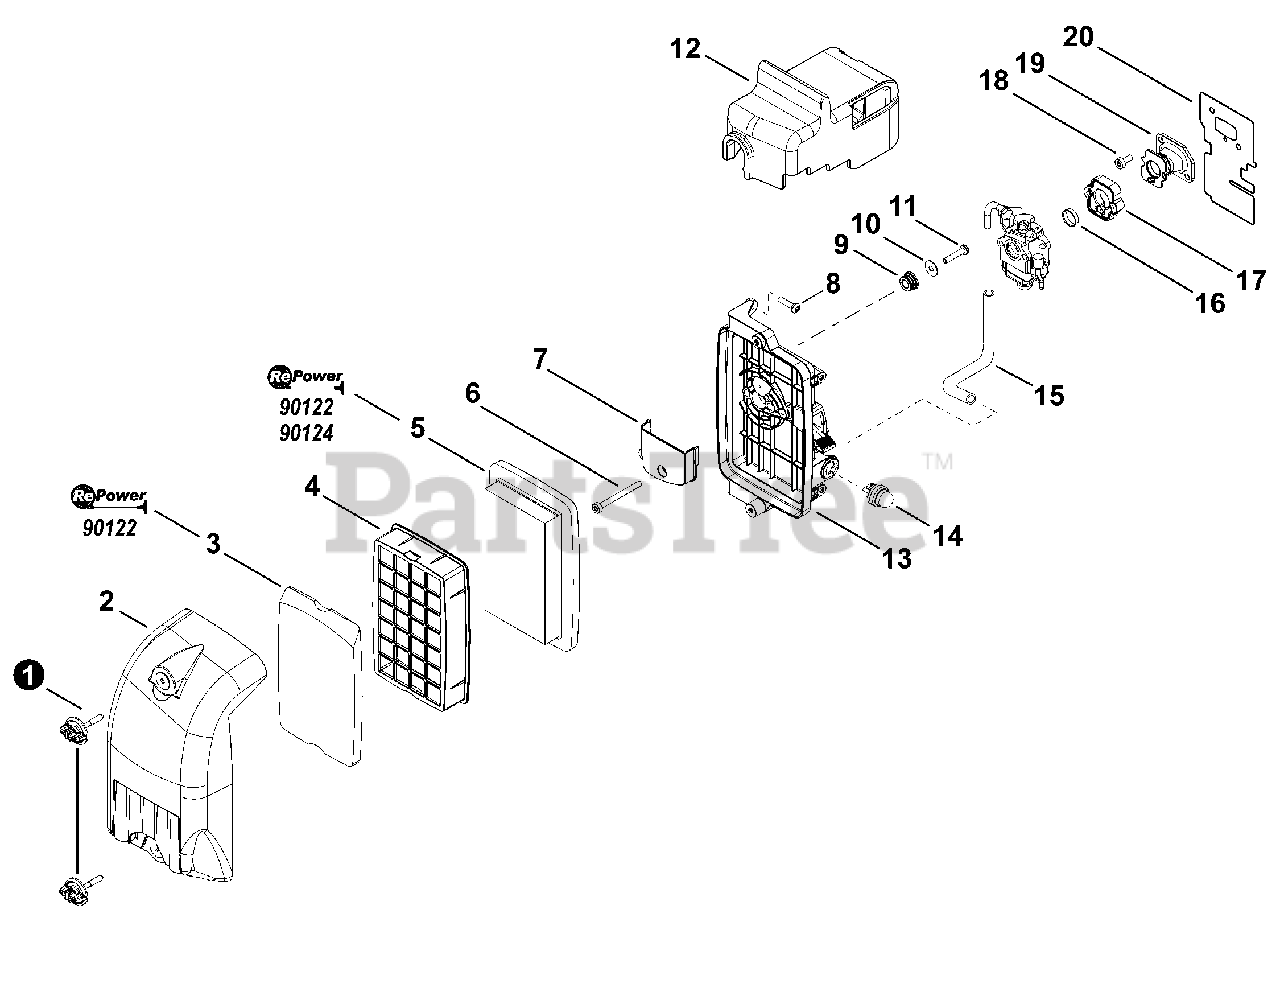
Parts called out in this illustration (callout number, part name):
1	THUMBSCREW
2	COVER, AIR FILTER
3	PRE-FILTER, FOAM
4	GRID, AIR FILTER
5	FILTER, AIR
6	BOLT, TORX 5×55
7	PLATE, PREVENT
8	BOLT, TORX 5×20
9	GUIDE, CABLE
10	WASHER 5.5×16×0.8
11	BOLT, TORX 5×16
12	CAP, CARBURETOR
13	CASE ASSY, AIR FILTER
14	BULB, PURGE
15	PIPE, PURGE 2.5×5×140
16	RING, SEAL
17	ADAPTOR, INTAKE
18	SCREW 5×12
19	BELLOWS, INTAKE
20	HEAT SHIELD, INTAKE
